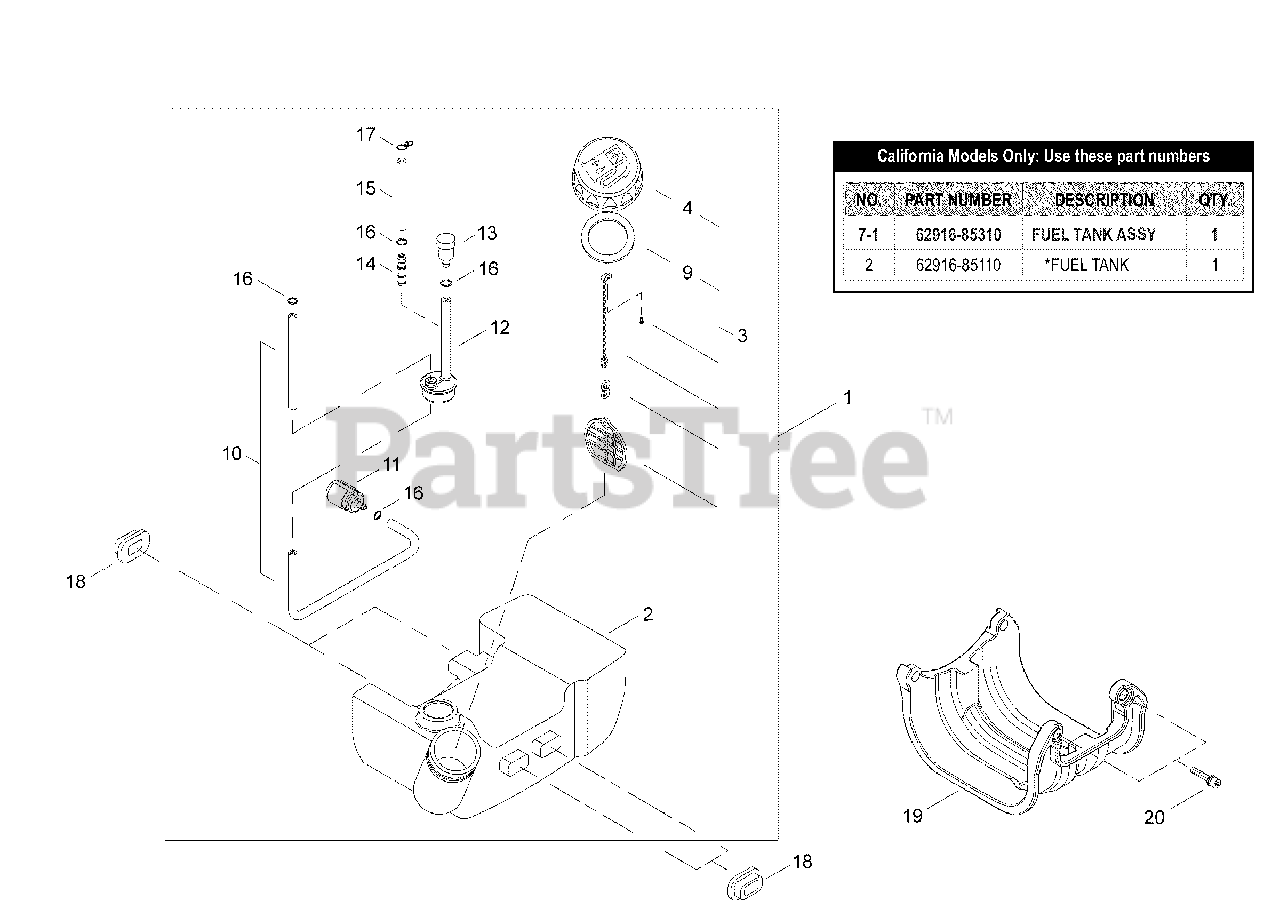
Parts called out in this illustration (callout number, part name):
1	FUEL TANK ASSY
2	TANK, FUEL
3	CAP ASSY
4	CAP, FUEL
9	GASKET, CAP
10	PIPE - FUEL
11	FILTER, FUEL
12	GROMMET
13	ELEMENT, BREATHER
14	CONNECTOR, PIPE
15	PIPE
16	RING, RETAINING - 6
17	CLIP - SPRING
18	CUSHION, FUEL TANK
19	GUARD, FUEL TANK
20	SCREW - 5X20
